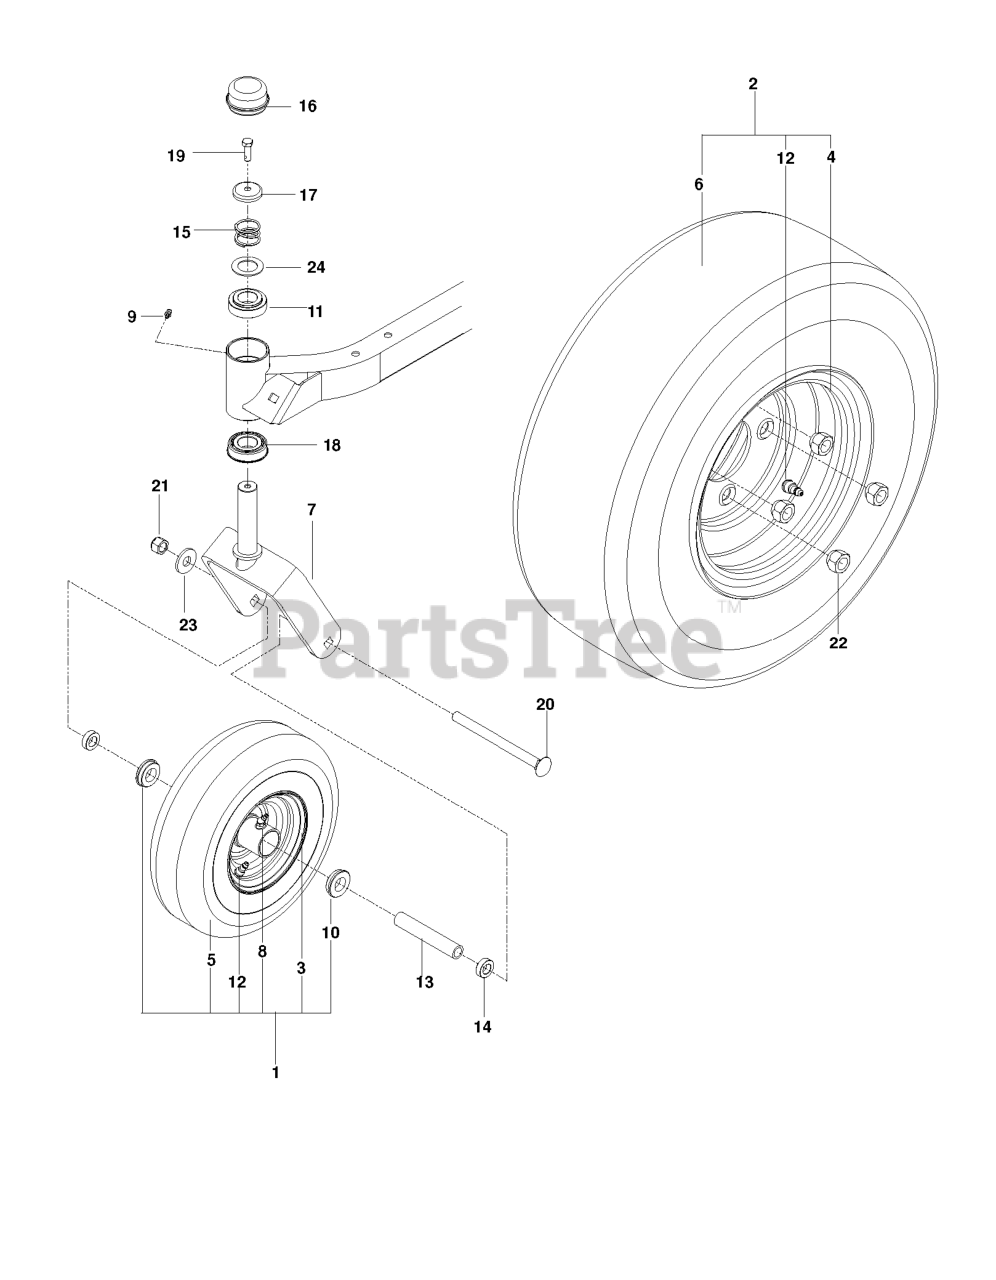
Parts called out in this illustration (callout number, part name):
1	TIRE.CASTER.ASSEM.11X4-5.GR
2	WHEEL ASSY REAR 18 X 7.5-8
4	RIM 5.375"X8"
5	TIRE.11"X4"-5.4PLY.SMOOTH.KEND
6	TIRE.KENDA.18X7.5-8.4PLY
7	YOKE.CASTER.ORANGE
8	ZERK
9	ZERK, 3/16, DRIVE IN
10	BUSHING, WHEEL, 3/4"
11	BUSHING, CASTER
12	VALVE STEM TR-412
14	SPACER, 5/16"
15	SPRING, CASTER
16	GREASE CAP
17	CASTER.PLUG
18	BEARING FLANGED
19	5/16-18X1 HHB G5W/NY
20	RHSNB 1/2-13 X 6.50 GR2 ZD
21	NUT 1/2-13 HEX CNTRLK GR 5 ZD
22	LUG NUT 1/2F
23	WASH USS FLAT 1/2
24	WASHER, 1.025 ID X 1.64
